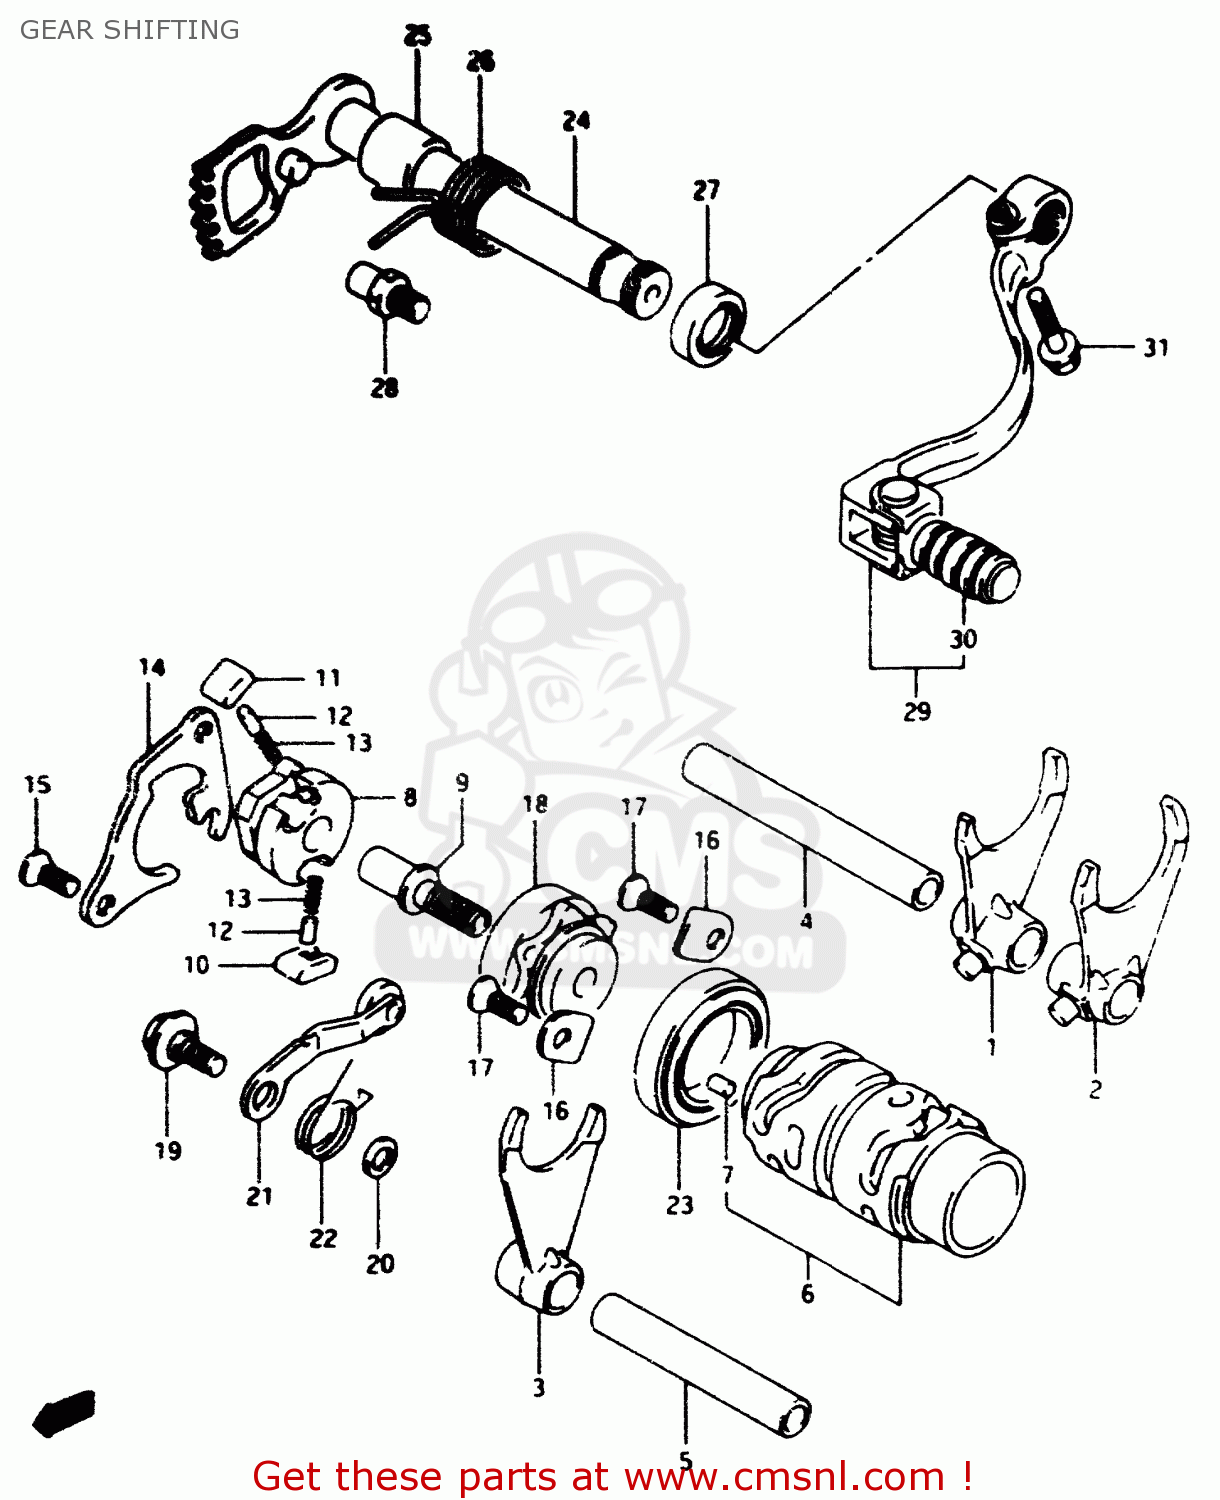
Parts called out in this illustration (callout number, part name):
1	FORK,GEAR SHIFT NO.1
2	FORK,GEAR SHIFT NO.2
3	FORK,GEAR SHIFT NO.3
4	SHAFT,GEAR SHIFT FORK
5	SHAFT,GEAR SHIFT FORK
6	CAM,GEAR SHIFT
7	PIN
8	GEAR,GEARSHIFT CAM DRIVE
9	PIN,SHIFT CAM DRIVEN GEAR
10	PAWL,GEAR SHIFT NO.1
11	PAWL,GEAR SHIFT NO.2
12	PIN(5X8)
13	SPRING
14	LIFTER,GEAR SHIFT POLE
15	SCREW
16	RETAINER,COUNTER BEARING,R
17	SCREW
18	PLATE,SHIFT CAM STOPPER
19	BOLT(6X14.3)
20	WASHER
21	STOPPER,SHIFT CAM
22	SPRING
23	BEARING
24	SHAFT,GEAR SHIFT
25	SPACER(14X20X17.5)
26	SPRING
27	SEAL,OIL(14X22X6)
28	STOPPER,GEAR SHIFT CAM
29	LEVER ASSEMBLY,GEAR SHIFTING
30	RUBBER,GEAR SHIFT PEDAL
31	BOLT,G/S SWITC
